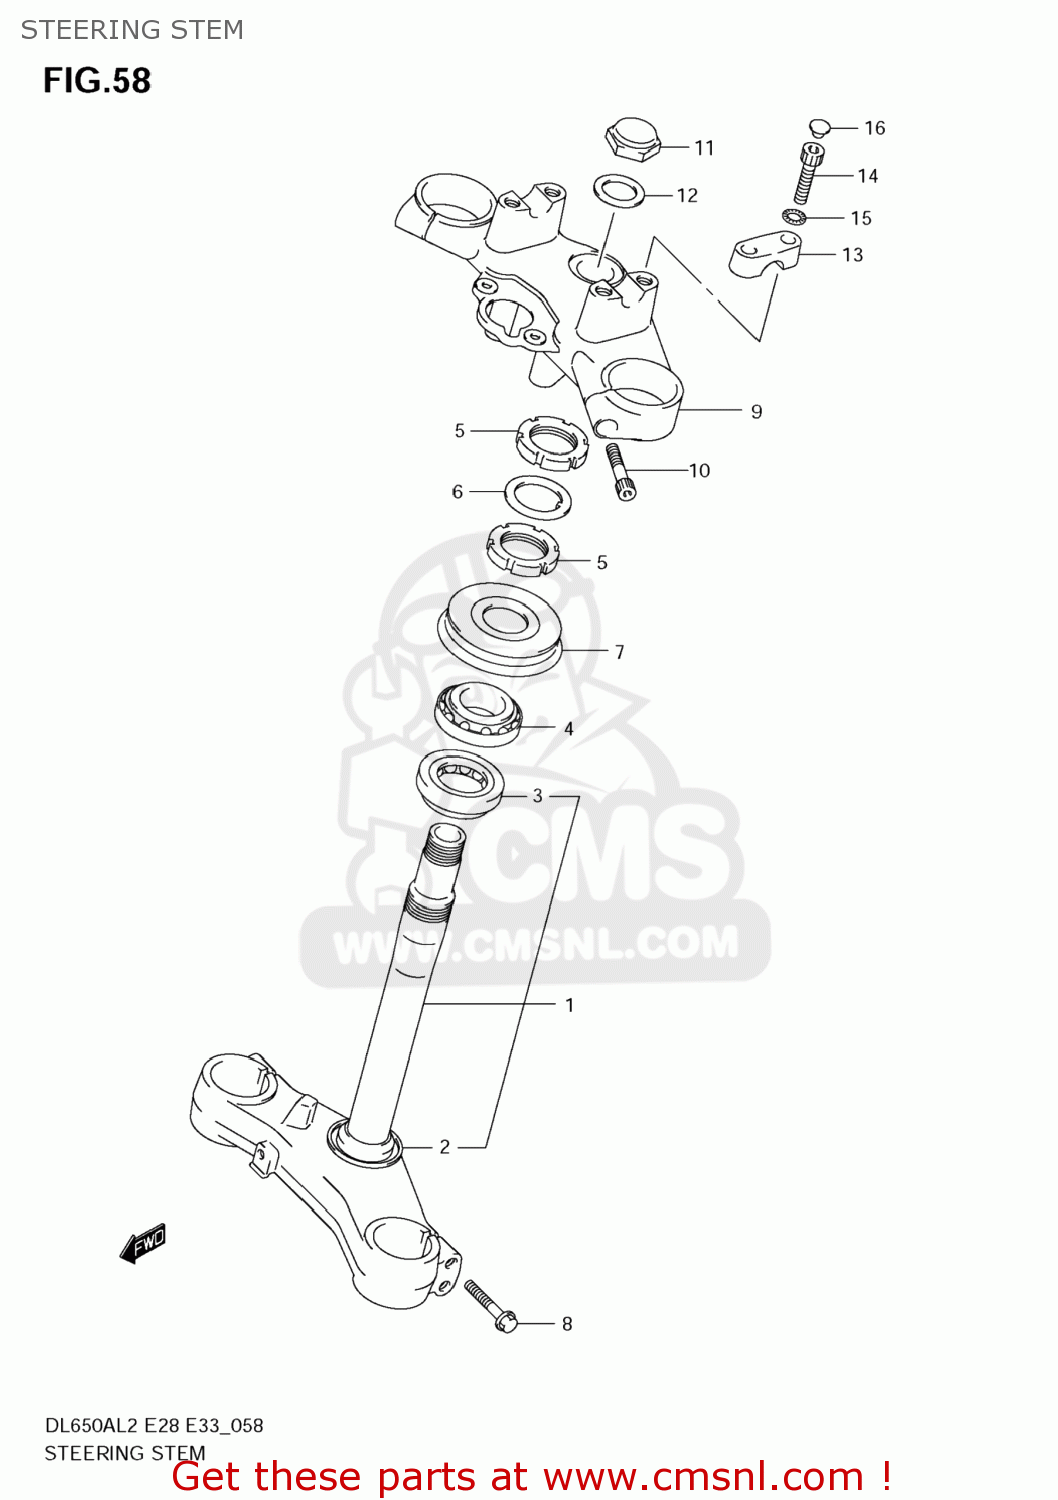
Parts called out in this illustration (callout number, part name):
1	STEM,STEERING
2	SEAL,STEERING LWR
3	BEARING(30X55X17)
4	BEARING(30X55X17)
5	NUT,STEERING STEM
6	WASHER,STEERING STEM
7	SEAL,STEERING UPR DUST
8	BOLT,HOLDER AXLE(8X40)
9	BRACKET,UPR
10	BOLT,OUTER,L(07130-08407)
11	NUT
12	WASHER
13	HOLDER,HANDLE UPR
14	BOLT,HANDLE HOLDER
15	WASHER
16	CAP(OD:11)
